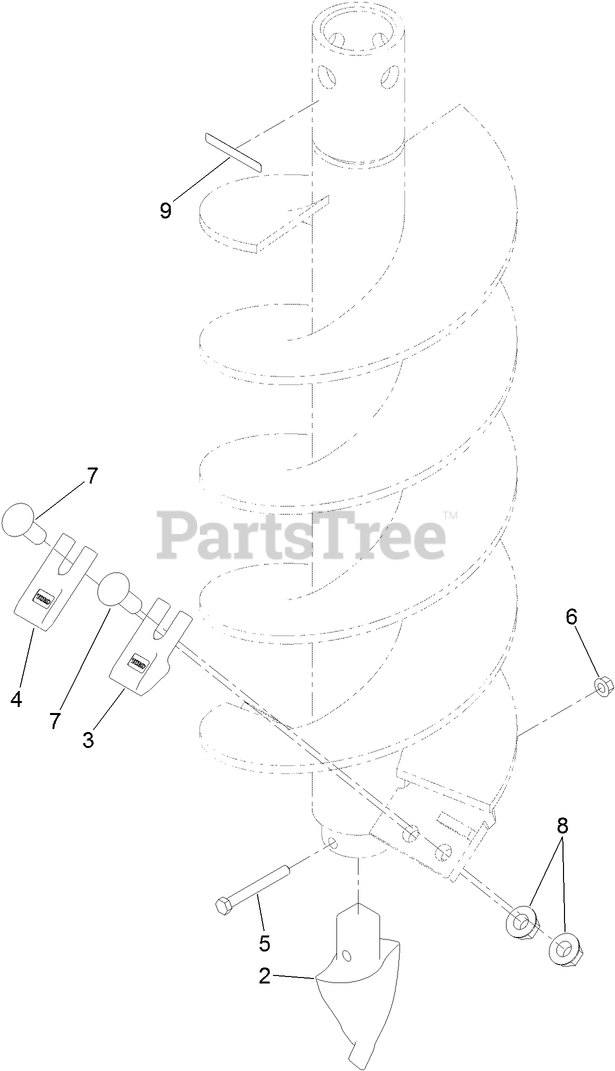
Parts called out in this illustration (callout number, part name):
2	PILOT-AUGER
3	TOOTH-OUTER
4	TOOTH-INNER
5	SCREW-HH
6	NUT-HF
7	SCREW-CARR
8	NUT-FLANGE
9	DECAL-WARNING
